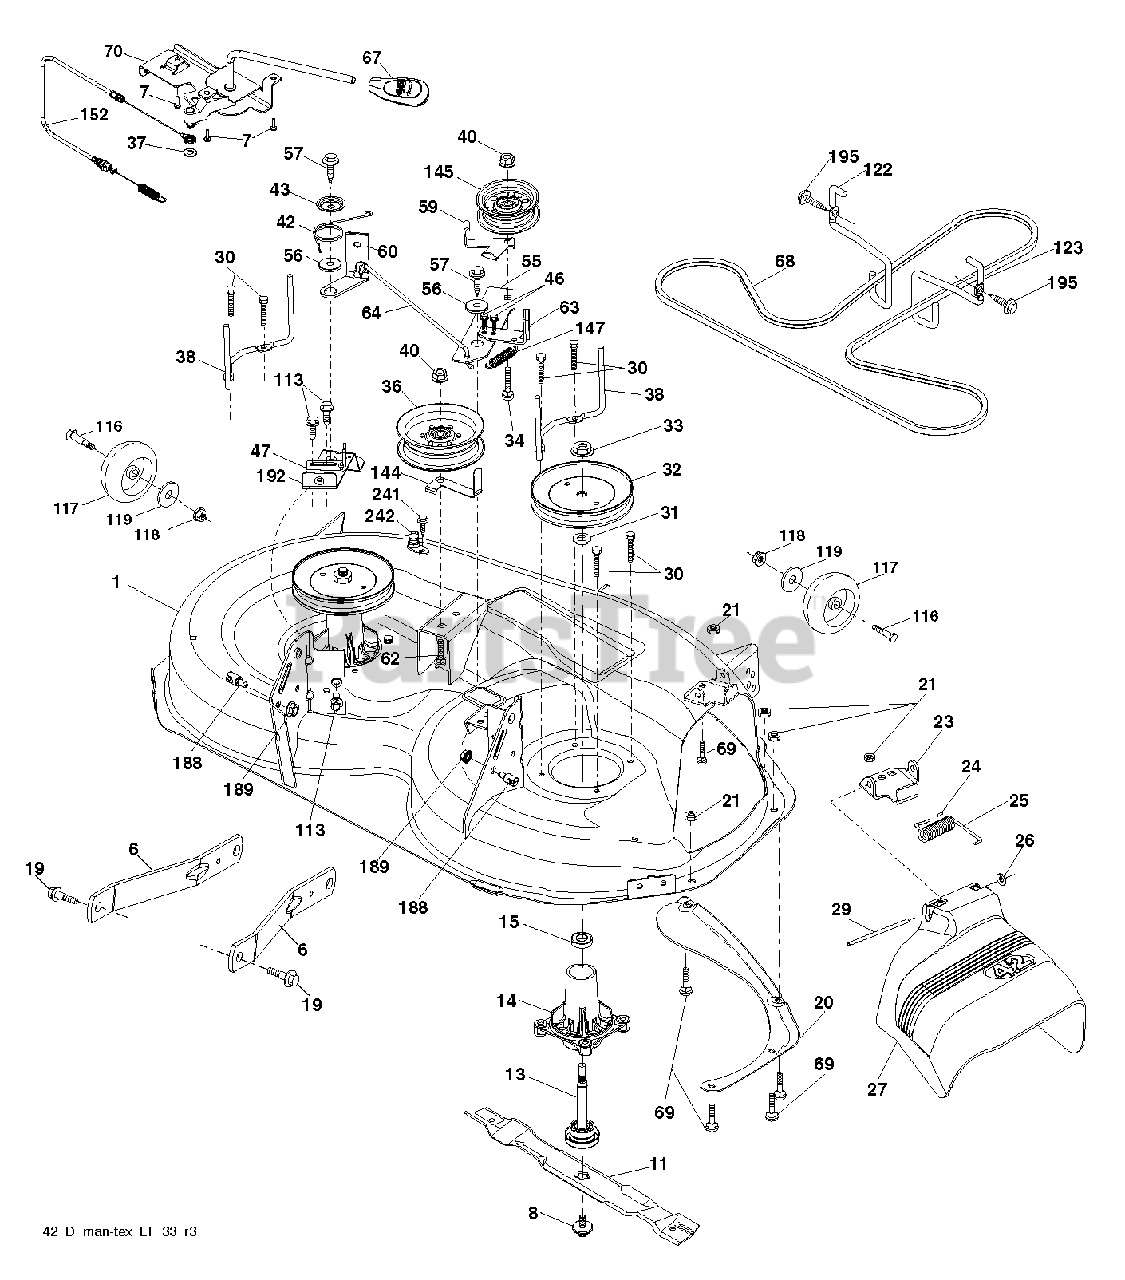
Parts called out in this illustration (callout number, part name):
1	DECK.WELDMENT.42"PAINT
6	ARM.SUSPENSION.MOWER.R
7	SCREW.#10 X 0.750.BOS
8	BOLT.WASHER.ASM.7/16-2
11	42" HI-LIFT BLADE
13	SHAFT.ASM.MDRL.N/GREASE.38
14	HOUSING.MANDREL.4PT.
19	BOLT.SHOULDER
20	BAFFLE.VORTEX
21	LOCKNUT
23	BRKT.DEFLECTOR.38"2005+
24	CAP-SLEEVE LT
25	SPRING.TORSION.DEFLECT
26	NUT PUSH M
27	SHIELD.DEFLECTOR.MOWER.42"BLAC
29	ROD.HINGE
30	SCREW, WASHER HEAD
31	WASHER.SPACER.MANDREL
32	PULLEY.MANDREL.5.438.PD
33	NUT.FLANGE.LOCK.TOP
34	BOLT.3/8-16X1.50
36	PULLEY.IDLER.2006
37	WASHER
38	KEEPER.BELT.MANDREL.PULLEY
40	NUT LOCK FLG 3/8-16 UNC
42	SPRING.TORSION.BRAKE
43	SRPING.TORSION.RETAINE
46	SCREW.1/4-20X5/8
47	BRKT.CLUTCH.CABLE
55	IDLER.ARM.42"
56	SPACER.RETAINER
57	SCREW 3/8-16X1
59	GUARD, BELT
60	ARM BRAKE MOWER
63	ARM BRAKE MOWER
64	LINKAGE.BRAKE.ASM.ZINC
67	HANDLE.CLUTCH.CABLE.LT
68	BELT.DECK.DRIVE.42"
69	BOLT
70	CLUTCH.ASM.CABLE.HUSQ.TEX
113	BOLT.5/16HEX.WHS.HD
116	BOLT M
117	WHEEL.GAGE.HALF.SPOKED
118	NUT LOCK FLG 3/8-16 UNC
119	WASHER
122	KEEPER BELT ENGINE LH
123	KEEPER BELT RH
144	KEEPER.BELT.MOWER
145	PULLEY.IDLER.48"PRIMARY
147	RETURN SPRING
152	CABLE CLUTCH MANUAL W/SPR.
188	STUD.FASTNER.W/ANTI-ROTATE
189	NUT LOCK HEX FLANGE 5/16-18
192	BRKT.BRAKE.STAND.LH.
195	SCREW, 3/8-16X3/4
241	SCREW.TT.#10-32X.5.3/8.FLANGE
242	PORT.WASHOUT
